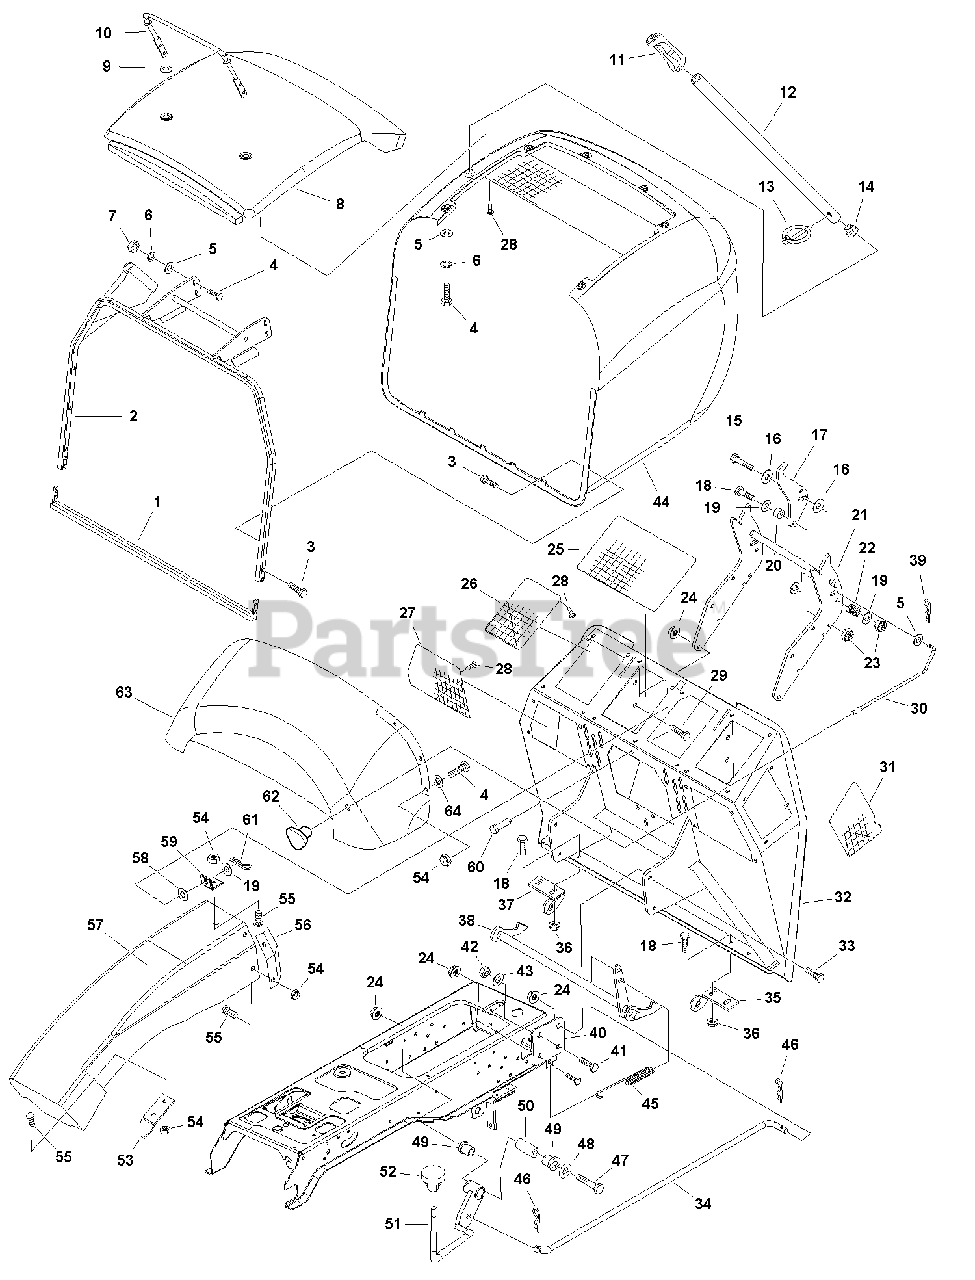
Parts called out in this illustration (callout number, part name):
1	ANGLE & BAR ASSEMBLY
2	FRAMEASSEMBLY, Hopper
3	CAPSCREW, Hex Head Taptite, 1/4-20 x 1/2
4	CAPSCREW, Hex Head, 1//4-20 x 7/8
5	WASHER, 1/4
6	LOCKWASHER, 1/4
7	NUT, 1/4-20
8	LID, Hopper, Red
9	WASHER, Rubber
10	HANDLE, Hopper
11	GRIP
12	TUBE, Handle
13	PIN, Click
14	CAP PLUG, Rubber
15	CAPSCREW, Hex Head, 5/16-18 x 2
16	WASHER, 5/16
17	LATCH, Pivot
18	CAPSCREW, Hex Head, 5/16-18 x 1
19	WASHER
20	SPACER
21	PIVOT ASSEMBLY
22	SPRING, Compression
23	NUT, Hex Lock ESNA Light, 5/16-18
24	NUT, Hex Flange Lock, 3/8-16
25	SCREEN, 1/4 Mesh, Top
26	SCREEN, Top Side, 5-1/2" x 7-3/4"
27	SCREEN, Main, 7" x 9"
28	FASTNER, Panel
29	CAPSCREW, Hex Head, 3/8-16 x 3/4
30	ROD, Latch
31	SCREEN, Side, 5" x 6-1/4"
32	BACKPLATE ASSEMBLY
33	CAPSCREW, Hex Head Whiz Lock, 3/8-16 x 1
34	ROD LATCH
35	BRACKET, Latch LH
36	NUT, Hex Flange Lock, 5/16-18
37	BRACKET, Latch, RH
38	SHAFT & ARMS ASSEMBLY
39	PIN, Cotter, 5/8 x 3.4
40	SUPPORT, Back Plate
41	CAPSCREW, Hex Head, 1/2-13 x 1
42	NUT, Hex, 1/2-13
43	LOCKWASHER, 1/2
44	HOPPER & SCREEN ASSEMBLY
45	SPRING, Extension
46	PIN, Hair
47	CAPSCREW, Hex Head, 3/8-16 x 2-1/2
48	WASHER
49	BUSHING
51	ROD & TUBE ASSEMBLY
52	KNOB, Hopper Release
53	RETAINER
54	NUT, Hex Lock ESNA, 1/4-20
55	SCREW, Torx Head, 1/4-20 x 5/8
56	DEFLECTOR, Grass
57	CHUTE, Discharge
58	NUT, Push
59	BRACKET, Chute
60	PIN, Clevis
61	PIN, Quick
62	KNOB
63	TRANSITION, Hopper
64	WASHER, 1/4
